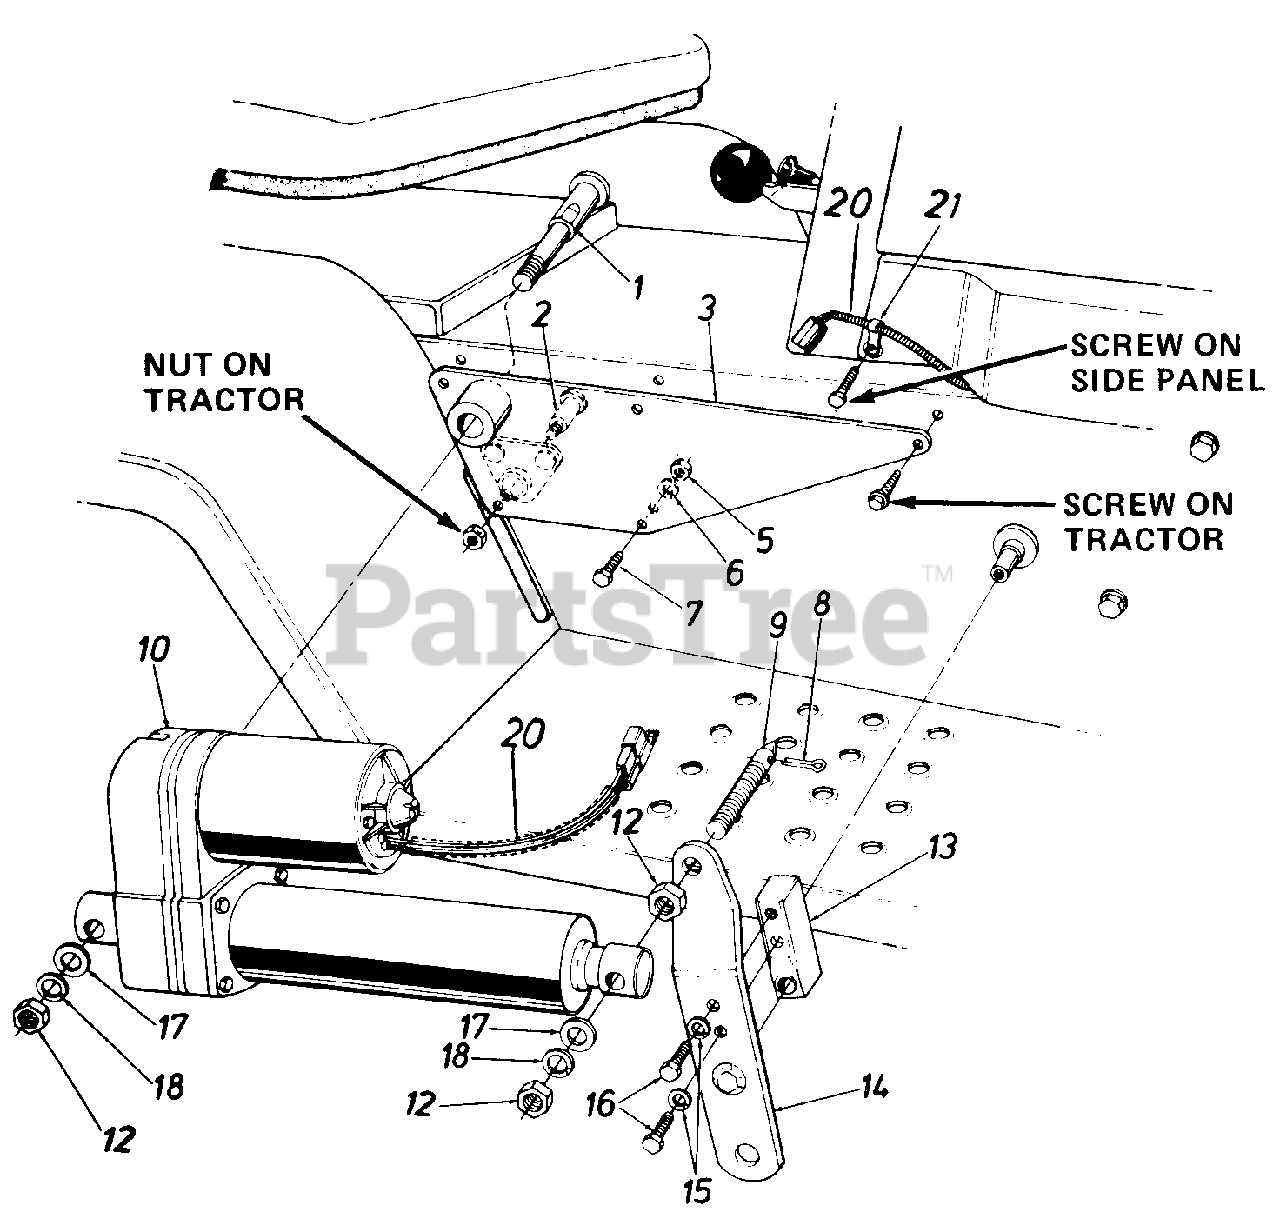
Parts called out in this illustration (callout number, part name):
2	Shld. Bolt.626 Dia. x .96"
5	Hex Nut 1/4-28Thd.
6	L-Wash. 1/4" I.D.*
7	Hex Bolt 1/4-28 x .75" Lg. (Grade 5)
9	Indicator & Mtg. Pin
10	Electric Actuator
12	Hex Jam Nut 1/2-13 Thd.
13	Lift Shaft Drive
16	Hex Bolt 5/16-24 x 1.0" Lg. (Grade 5)
17	Fl-Wash. .53" I.D. x.93" O.D.
18	L-Wash. 1/2" I.D.*
20	Plastic Tubing-7"
